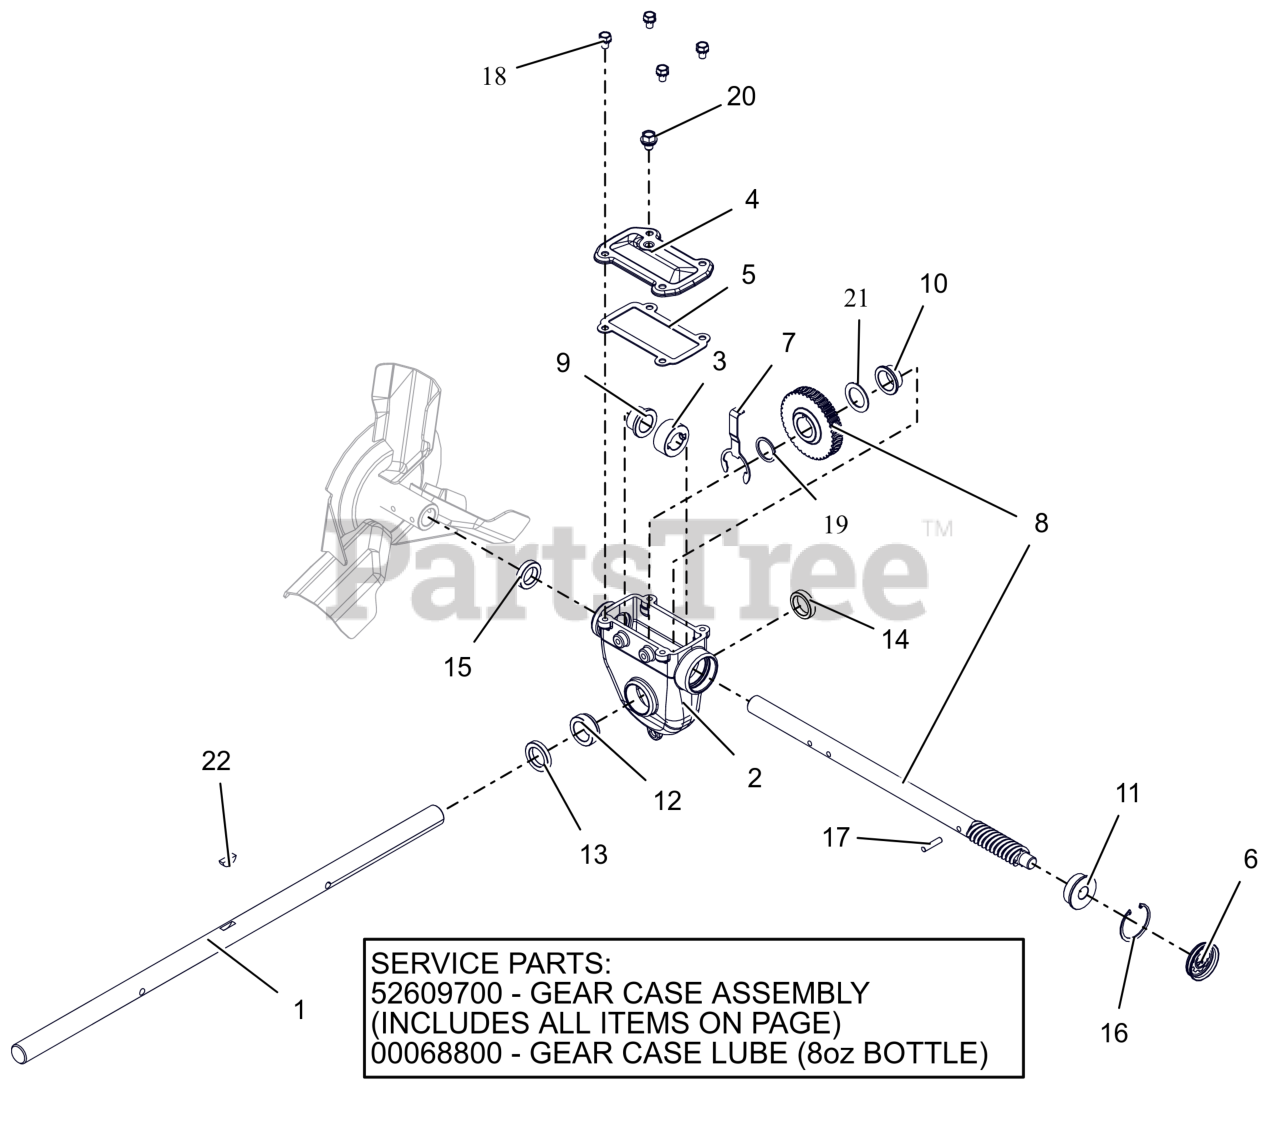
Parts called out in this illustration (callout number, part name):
1	SHAFT, RAKE-28"
2	GEARCASE, LARGE MACHINED
2	GEAR CASE, 28" IRON PRO TOP-LD
2	ARIENS L3 LUBE, 8 OZ BOTTLE
3	THRUST COLLAR, .875"ID SLIPFIT
4	COVER, TOP - LARGE IRON
5	GASKET, TOP - LARGE GEARCASE
6	COVER, GEAR CASE 1.75"
7	BUSHING RETAINER, LARGE
8	ASSY, WORM SHAFT & GEAR
9	BSHG-FLG .879X1.128X.75X1.45
10	BSHG-FLG 1.006X1.128X.555X1.45
11	BSHG-FLG .628X1.503X.58X1.725
12	BSHG-FLG LARGE, RIGHT
13	SEAL-OIL .999X1.500X.250 TBC29
14	SEAL-OIL .999X1.375X.312 TBC29
15	SEAL-OIL .873X1.375X.312 TBC29
16	RG-RTNG-INT 1.750X.062
17	PIN-STR .250X1.12 6150
18	BLT, SEMS .31-18X.50 G5 ZCC
19	WSHR, FLT 1.010X1.250X.068 ZCC
20	SCR, .380-15X.500 W/SEAL WASHER
21	WSHR, FLT 1.010X1.505X.062 ZCC
22	KEY-WDRF .25X.875 HRD #A
